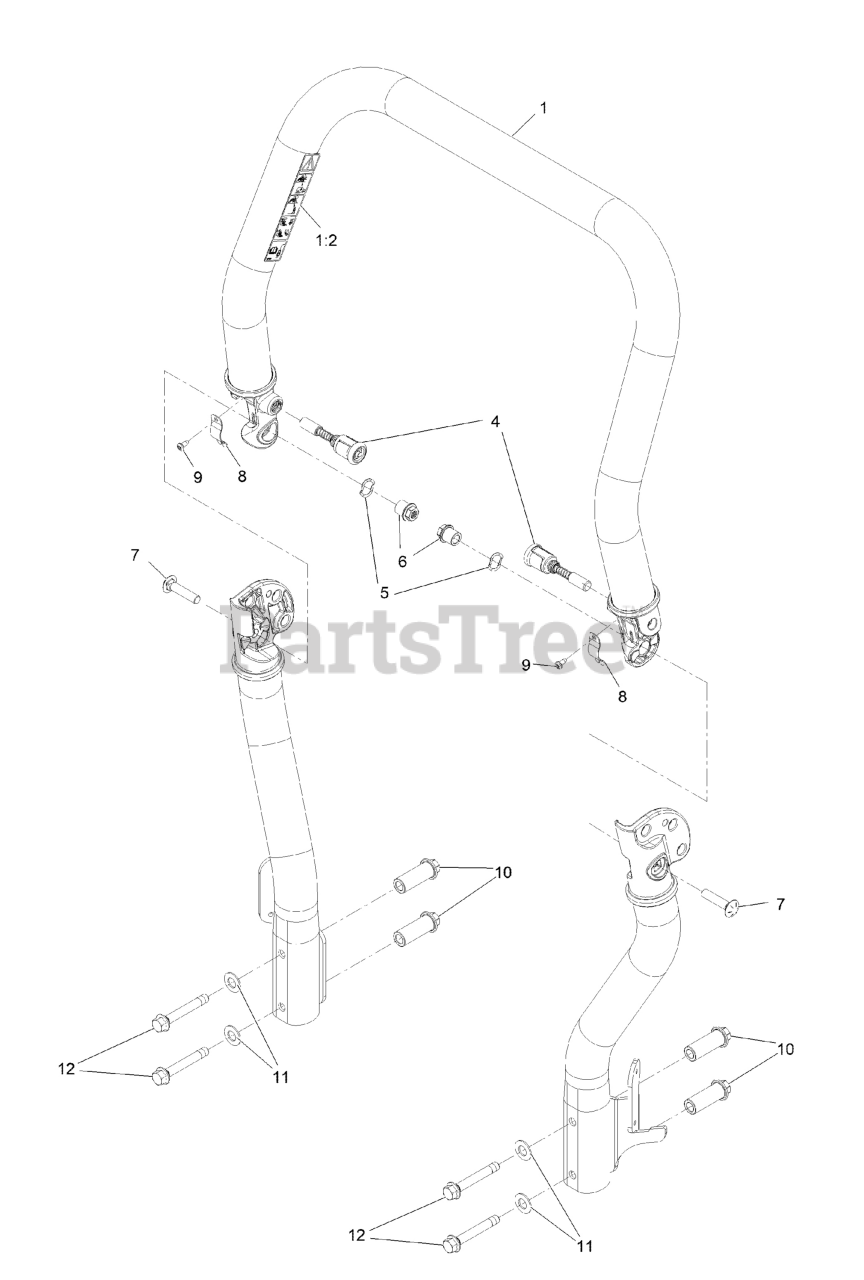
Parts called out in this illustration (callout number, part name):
1	ASM, ROPS Upper W/ Decal
1:2	DECAL-WARNING
4	PIN-SPRING
5	WASHER, WAVE
6	Nut, ROPS Pivot
7	Bolt,CARR, Spcl
8	SPRING, LEAF
10	SPACER, ROPS
11	Bolt, Shoulder
12	WASHER, BELLEVILLE
